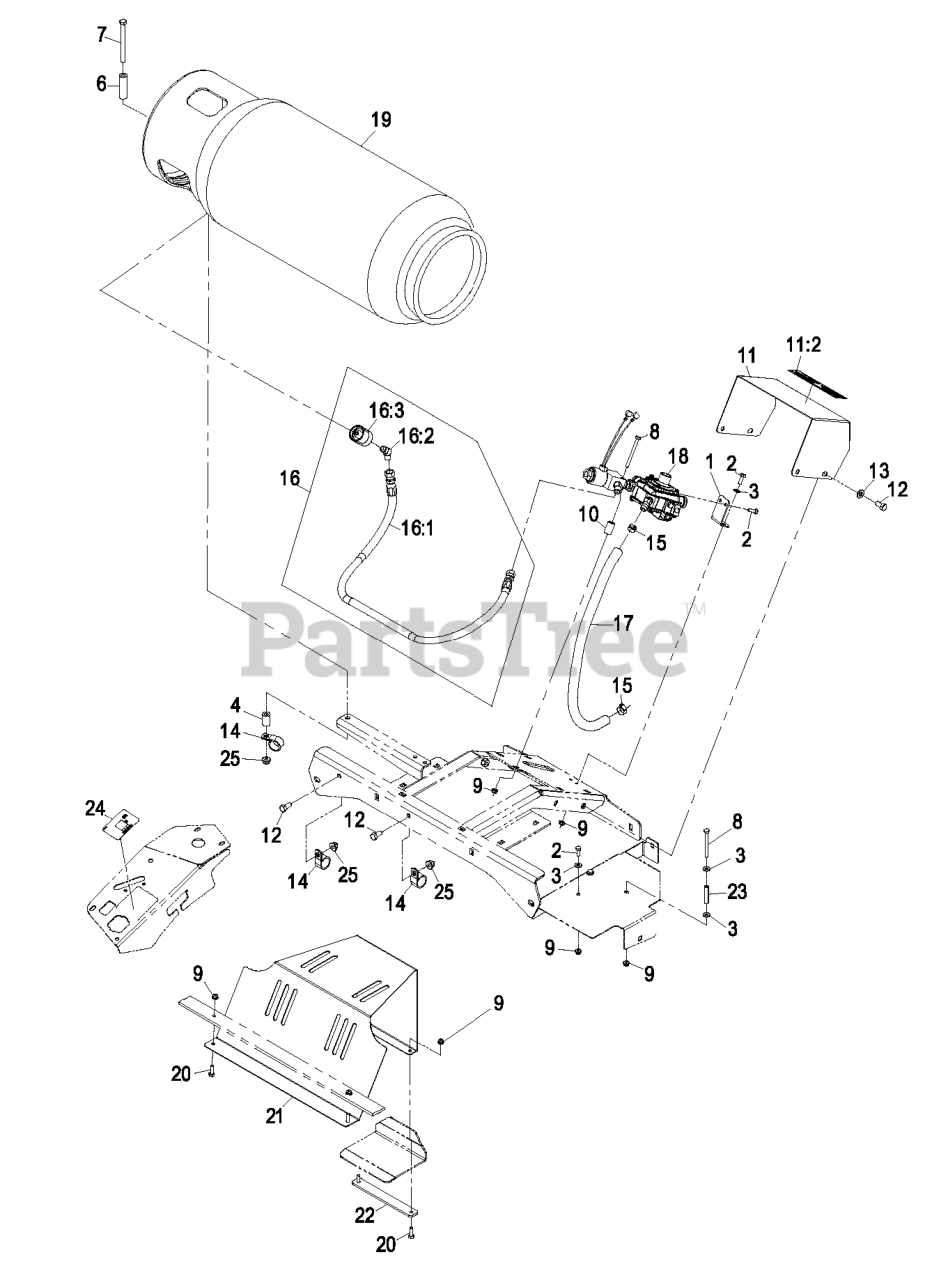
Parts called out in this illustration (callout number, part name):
1	BRACKET-REGULATOR
2	SCREW-HH
3	WASHER-FLAT
4	SPACER-HYDRO CONTROL, LH
6	SPACER-ANCHOR, CLUTCH
7	SCREW-HH
8	SCREW-HH
11	COVER ASM
11:2	DECAL-TANK REPLACEMENT
12	SCREW-HH
13	WASHER-FLAT
14	CLIP-LOOM
15	CLAMP-HOSE
16	LPG FUEL HOSE ASM
16:1	HOSE-LPG 38 IN.
16:2	ELBOW-45 DEG
16:3	CONNECTOR-LPG TANK, LH TH
17	HOSE-LP
18	Asm, Regulator Lp Solenoid
20	SCREW-HH
21	SHEILD-FAN
23	SPACER-SPLIT
24	DECAL-METER, HOUR
25	NUT-HF, NI
